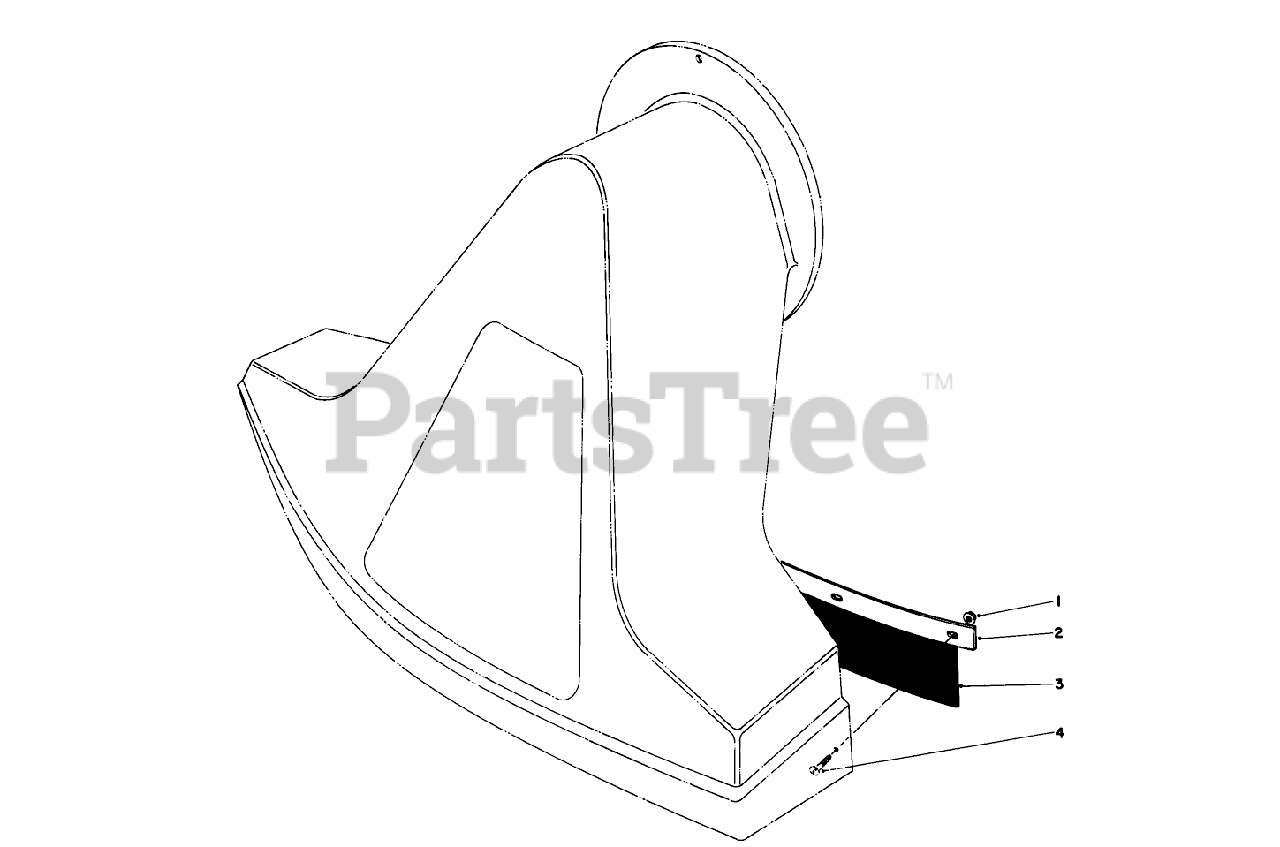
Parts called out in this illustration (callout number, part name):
1	Flange Nut
2	Clamp-Flap
3	FLAP-RUBBER
4	10-24 X 5/8 PAN HD MS
